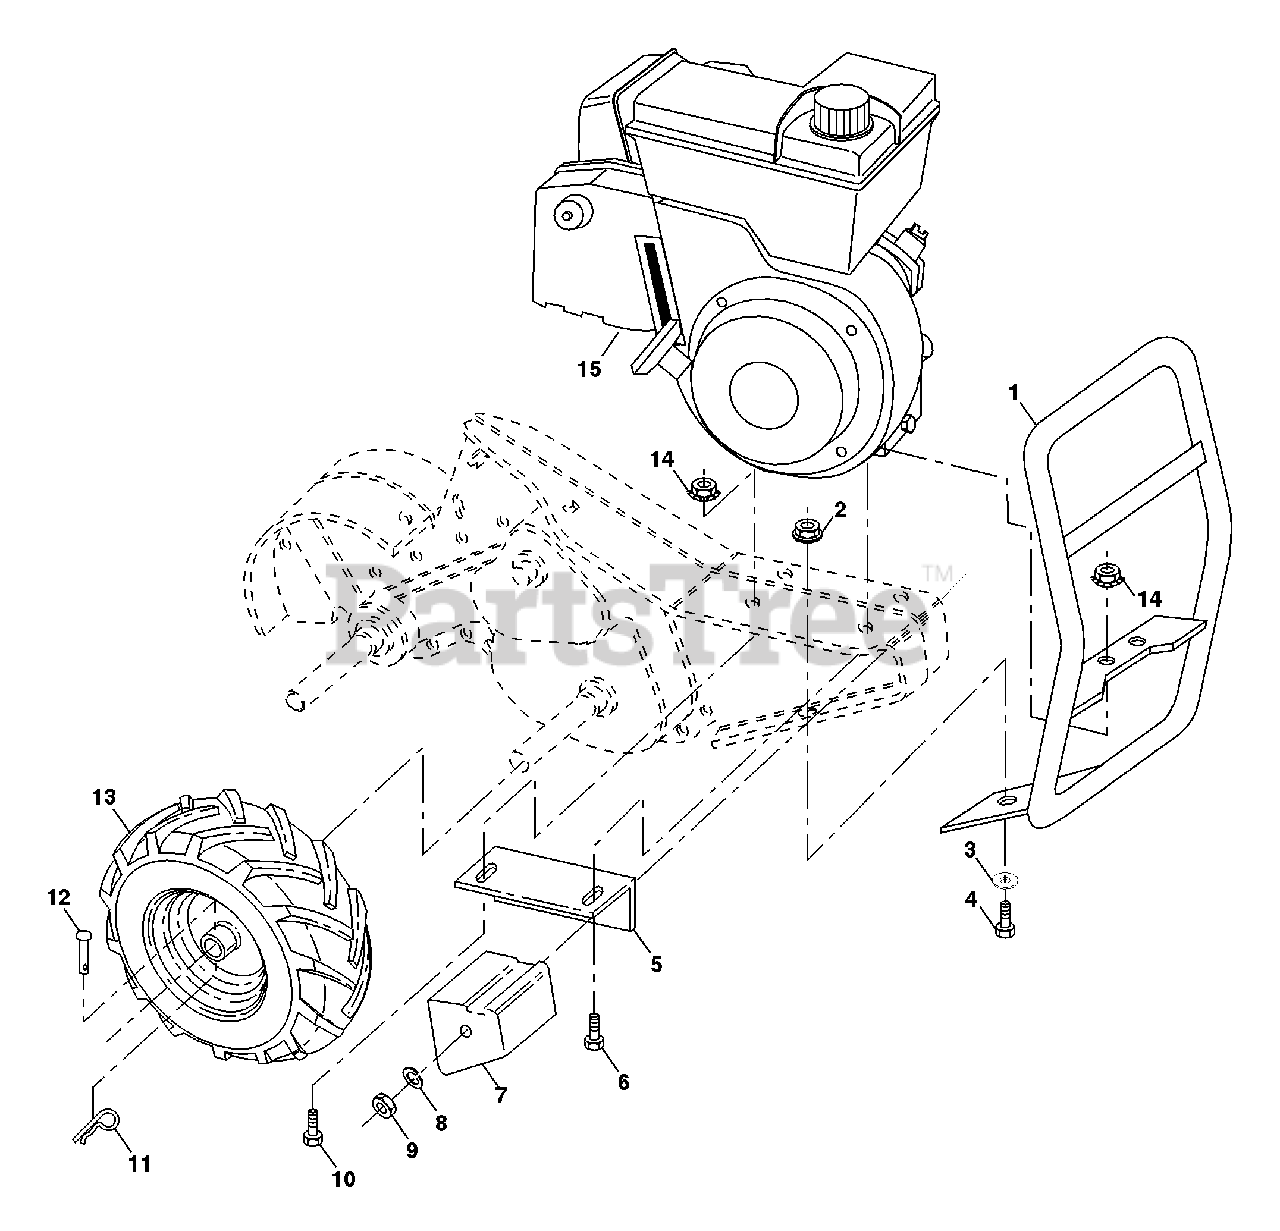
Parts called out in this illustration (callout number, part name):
2	Locknut, Hex Flange 5/16-18
3	Washer 11/32 x 11/16 x 16 Ga
4	Bolt, Hex 5/16-18 x 3/4
5	Bracket, Reinforcement
6	Bolt, Hex 5/16-18 x 2
7	Counter Weight, R.H.
8	Washer, Lock 3/8
9	Nut, Hex 3/8-16
10	Bolt, Hex 5/16-18 x 1-1/2
11	Clip, Hairpin
12	Rivet, Drilled
13	Rim
13	Tire Valve
14	Nut, Keps 5/16-18
15	Engine
